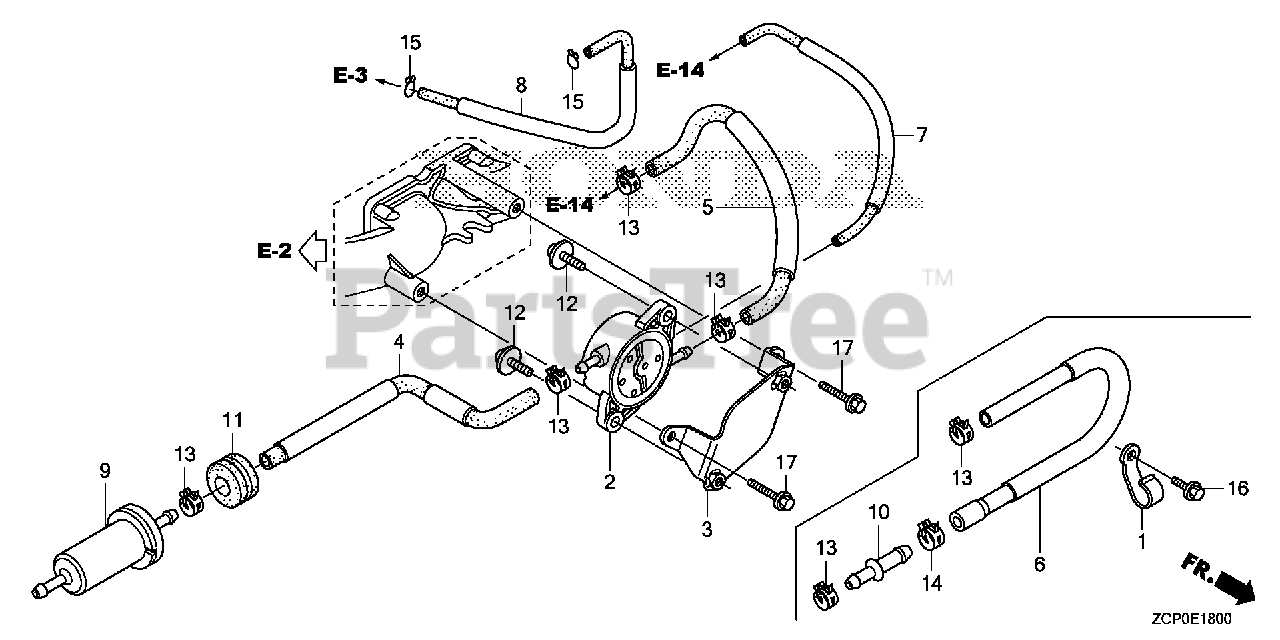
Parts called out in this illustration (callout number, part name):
2	PUMP ASSY., FUEL (MSDS)
3	STAY, FUEL PUMP
4	TUBE A, FUEL (FKM)
5	TUBE B, FUEL (FKM)
7	TUBE, PURGE
8	TUBE, DIAPHRAGM
9	FILTER, FUEL
11	RUBBER, RR. FENDER
12	SCREW-WASHER (6X16)
13	CLAMP, TUBE (D10)
15	CLIP, TUBE (C11)
17	BOLT, FLANGE (6X14)
